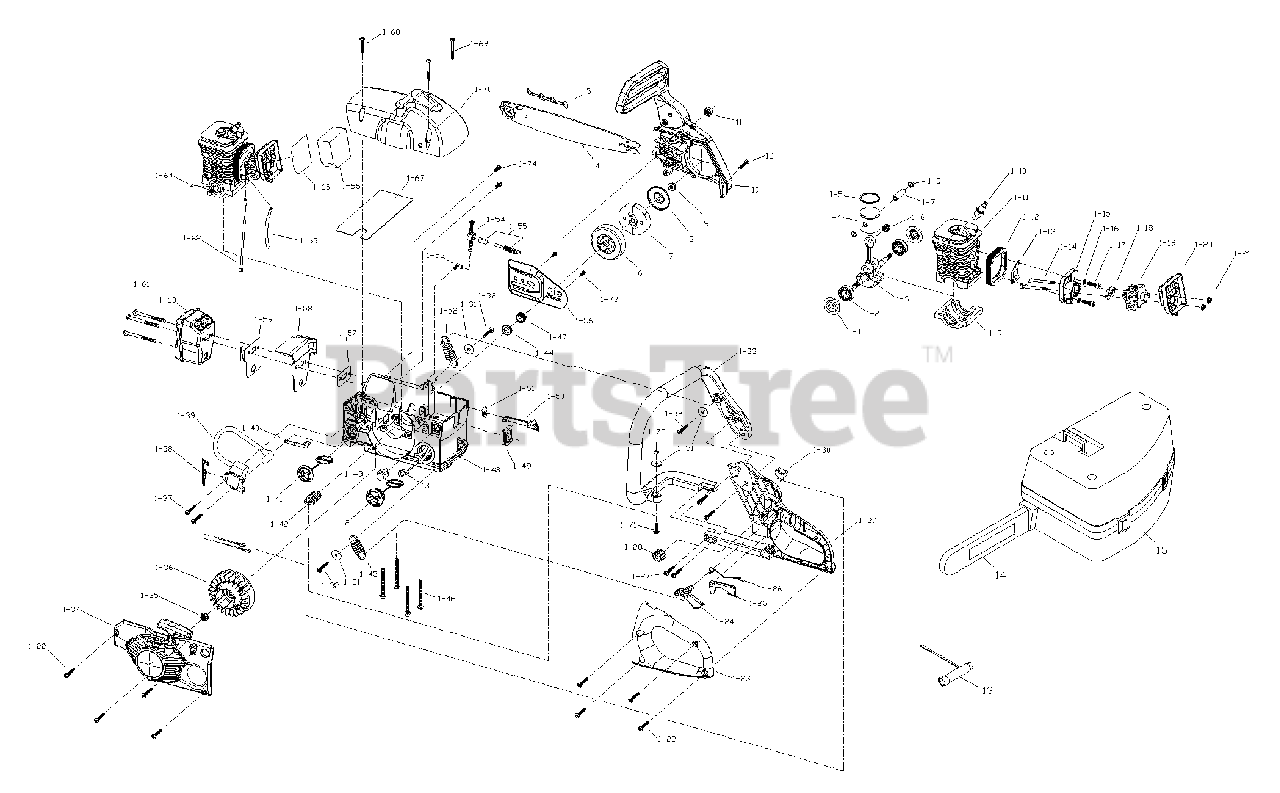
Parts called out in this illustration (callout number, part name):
1	ENG ASS'Y
1-1	CAP, BEARING
1-3	CRANK/ROD ASS'Y
1-5	RING, PISTON
1-6	ROLLER, PISTON
1-7	PIN, PISTON
1-9	CASE, CRANK
1-10	SPARK PLUG
1-12	RUBBER, ISOLATOR
1-16	SPRING WASHER
1-19	CARBURETOR
1-20	AIR FILTER ASS/Y
1-23	HANDLE, LEFT PART
1-24	TRIGGER, THROTTLE
1-25	TRIGGER, RELEASE
1-29	HANDLE, REAR
1-33	HANDLE, FRONT
1-34	STARTER HOUSING ASS'Y
1-38	WIRE ASS'Y
1-39	IGNITION ASS'Y
1-40	CONDUCTIVE PLATE
1-41	OIL CAP ASS'Y
1-42	SPRING ASS'Y
1-48	HOUSING ASS'Y
1-49	HOLDER, CABLE
1-50	LEVER, CHOKE
1-51	HOLDER, CHOKE LEVEL
1-53	CONNECTOR
1-55	PUMP ASS'Y
1-56	CAP, ANTI-DUST
1-60	MUFFLER ASS'Y
1-62	CABLE, THROTTLE
1-63	FUEL PIPE
1-64	WOODRUFF KEY
1-66	FILTER, AIR
2	FUEL CAP ASS'Y
4	BAR (MS1636AVCC)
5	CHAIN (MS1636AVCC)
6	DRUM ASS'Y
7	CLUTCH ASS'Y
8	CAP, ANTI-DUST
10	BRAKE KIT ASS'Y
15	CARRY CASE
